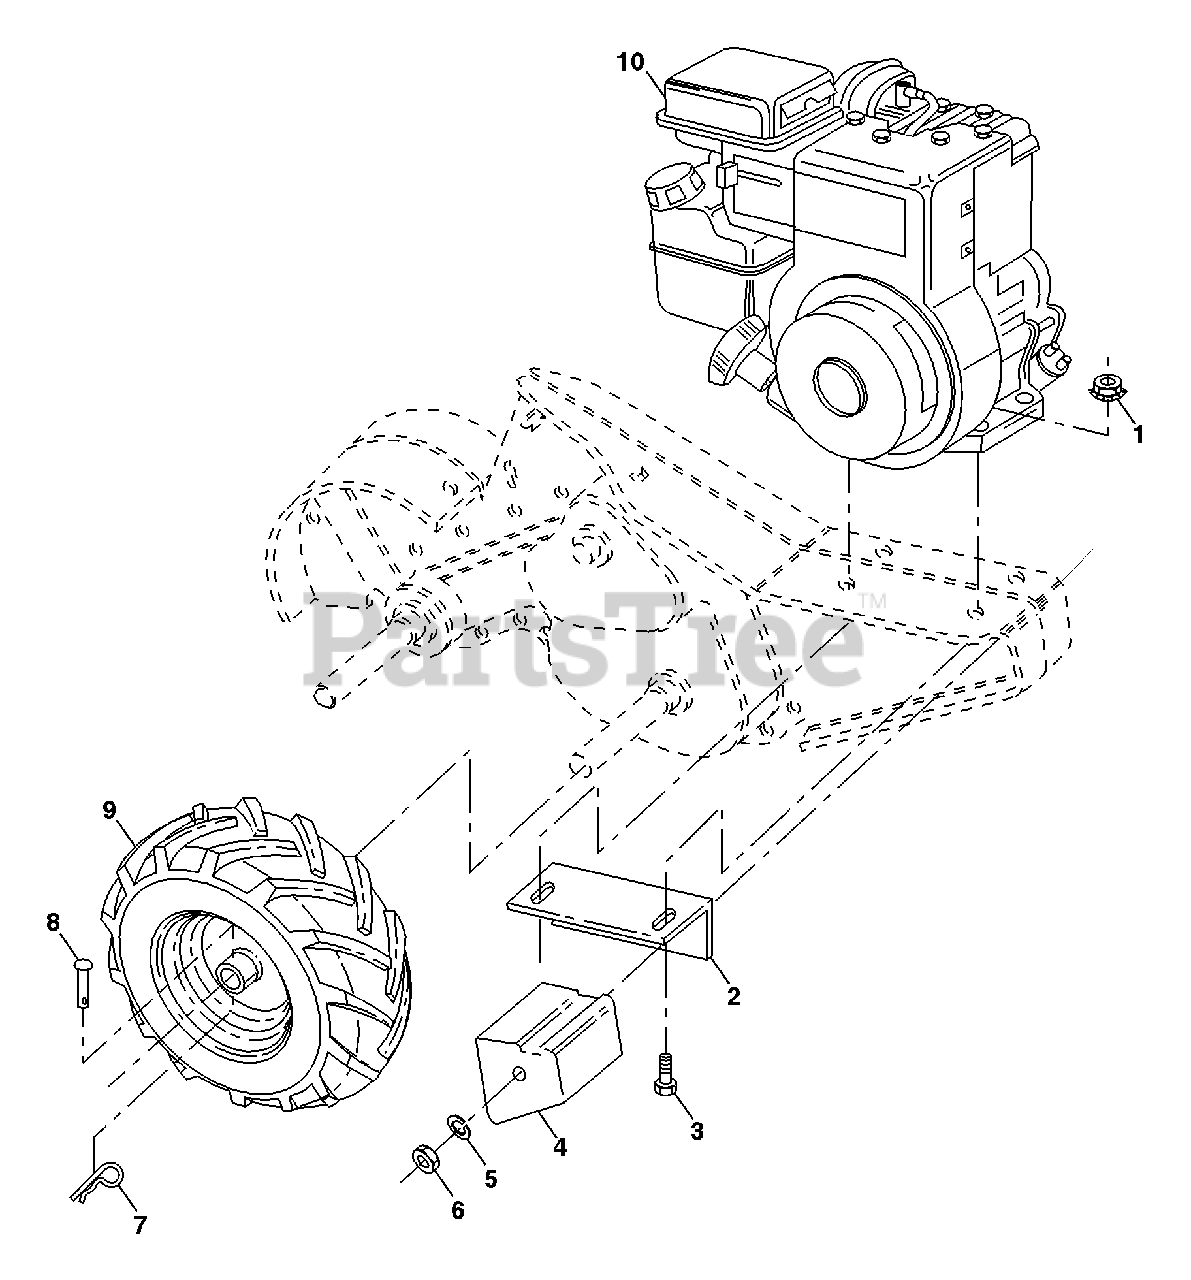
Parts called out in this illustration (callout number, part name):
1	Nut, Keps 5/16-18
2	Bracket, Reinforcement
3	Bolt, Hex 5/16-18 x 1-1/2
4	Counter Weight, R.H.
5	Washer, Lock 3/8
6	Nut, Hex 3/8-16
7	Clip, Hairpin
8	Rivet, Drilled
9	Rim
9	Tire Valve
10	Engine
